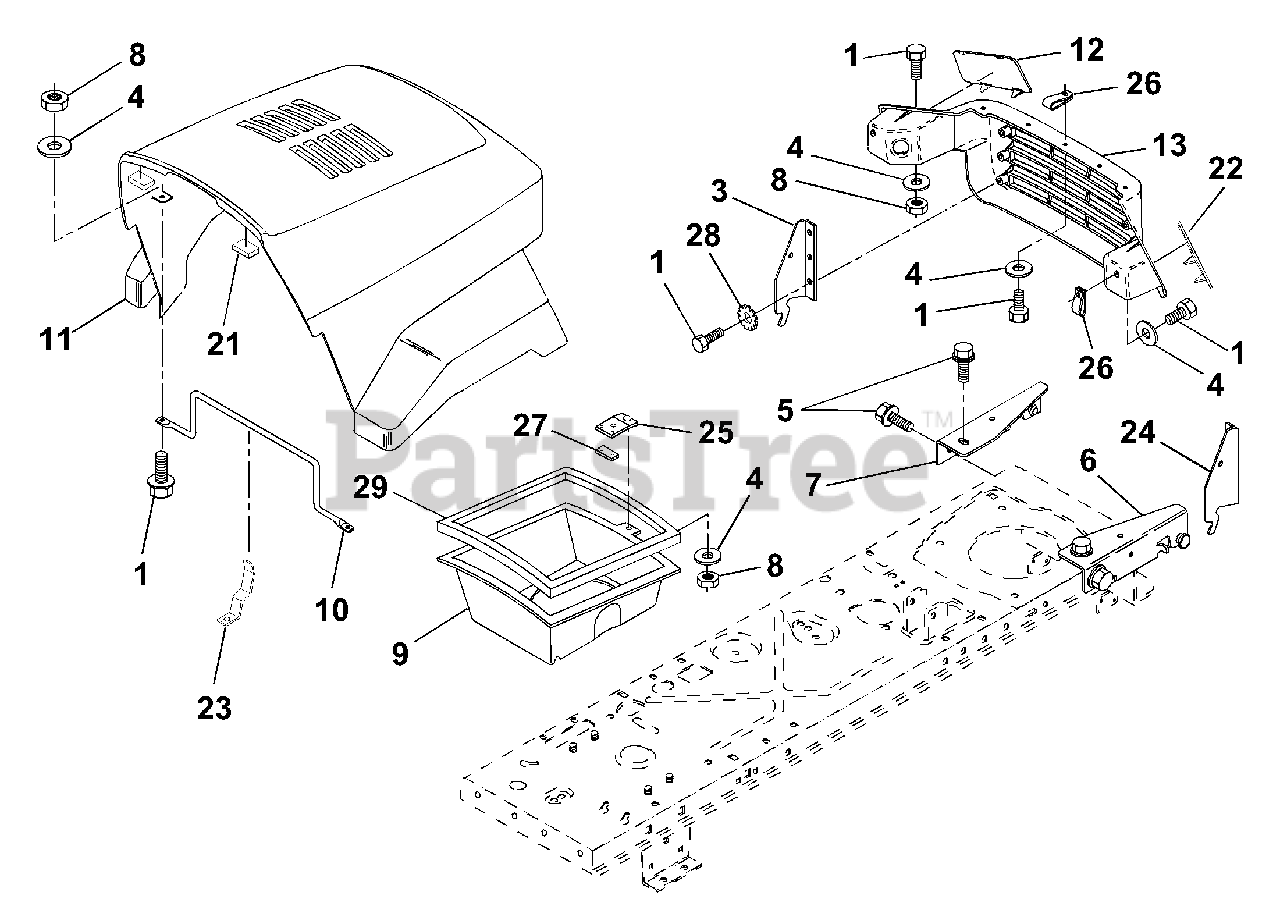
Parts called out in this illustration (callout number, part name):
1	Bolt Fin Hex 1/4-20 x 5/8
3	Bracket Pivot Hood LH
4	Washer, Flat 1/4
5	Screw Thdrol 5/16-28 x 3/4
6	Bracket Asm. Pivot Hood RH
7	Bracket Asm. Pivot Hood LH
8	Nut Fin Hex 1/4-20
9	Duct Air Hood
10	Brace Hood
13	Grille
21	Bumper Hood
23	Latch Hood
24	Bracket Pivot Hood RH
25	Clip Asm. Duct Air
26	Clip Tinnerman
27	Clip Tinnerman
28	Washer Lock Ext. Tooth
29	Strip Foam
